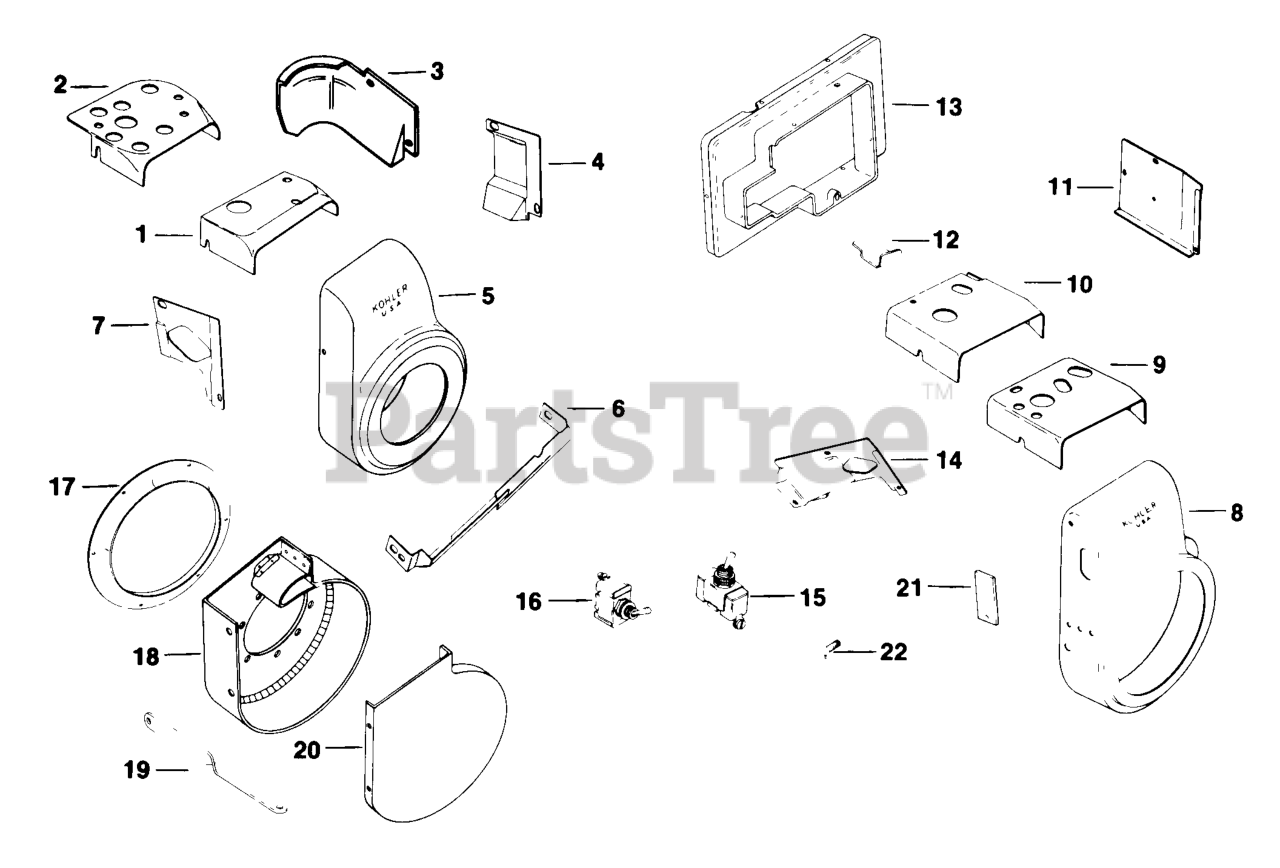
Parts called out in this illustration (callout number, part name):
1	BAFFLE, HEAD
4	BAFFLE, CYLINDER
7	BAFFLE, SIDE AIR
8	KIT, HOUSING - DISCONTINUED
